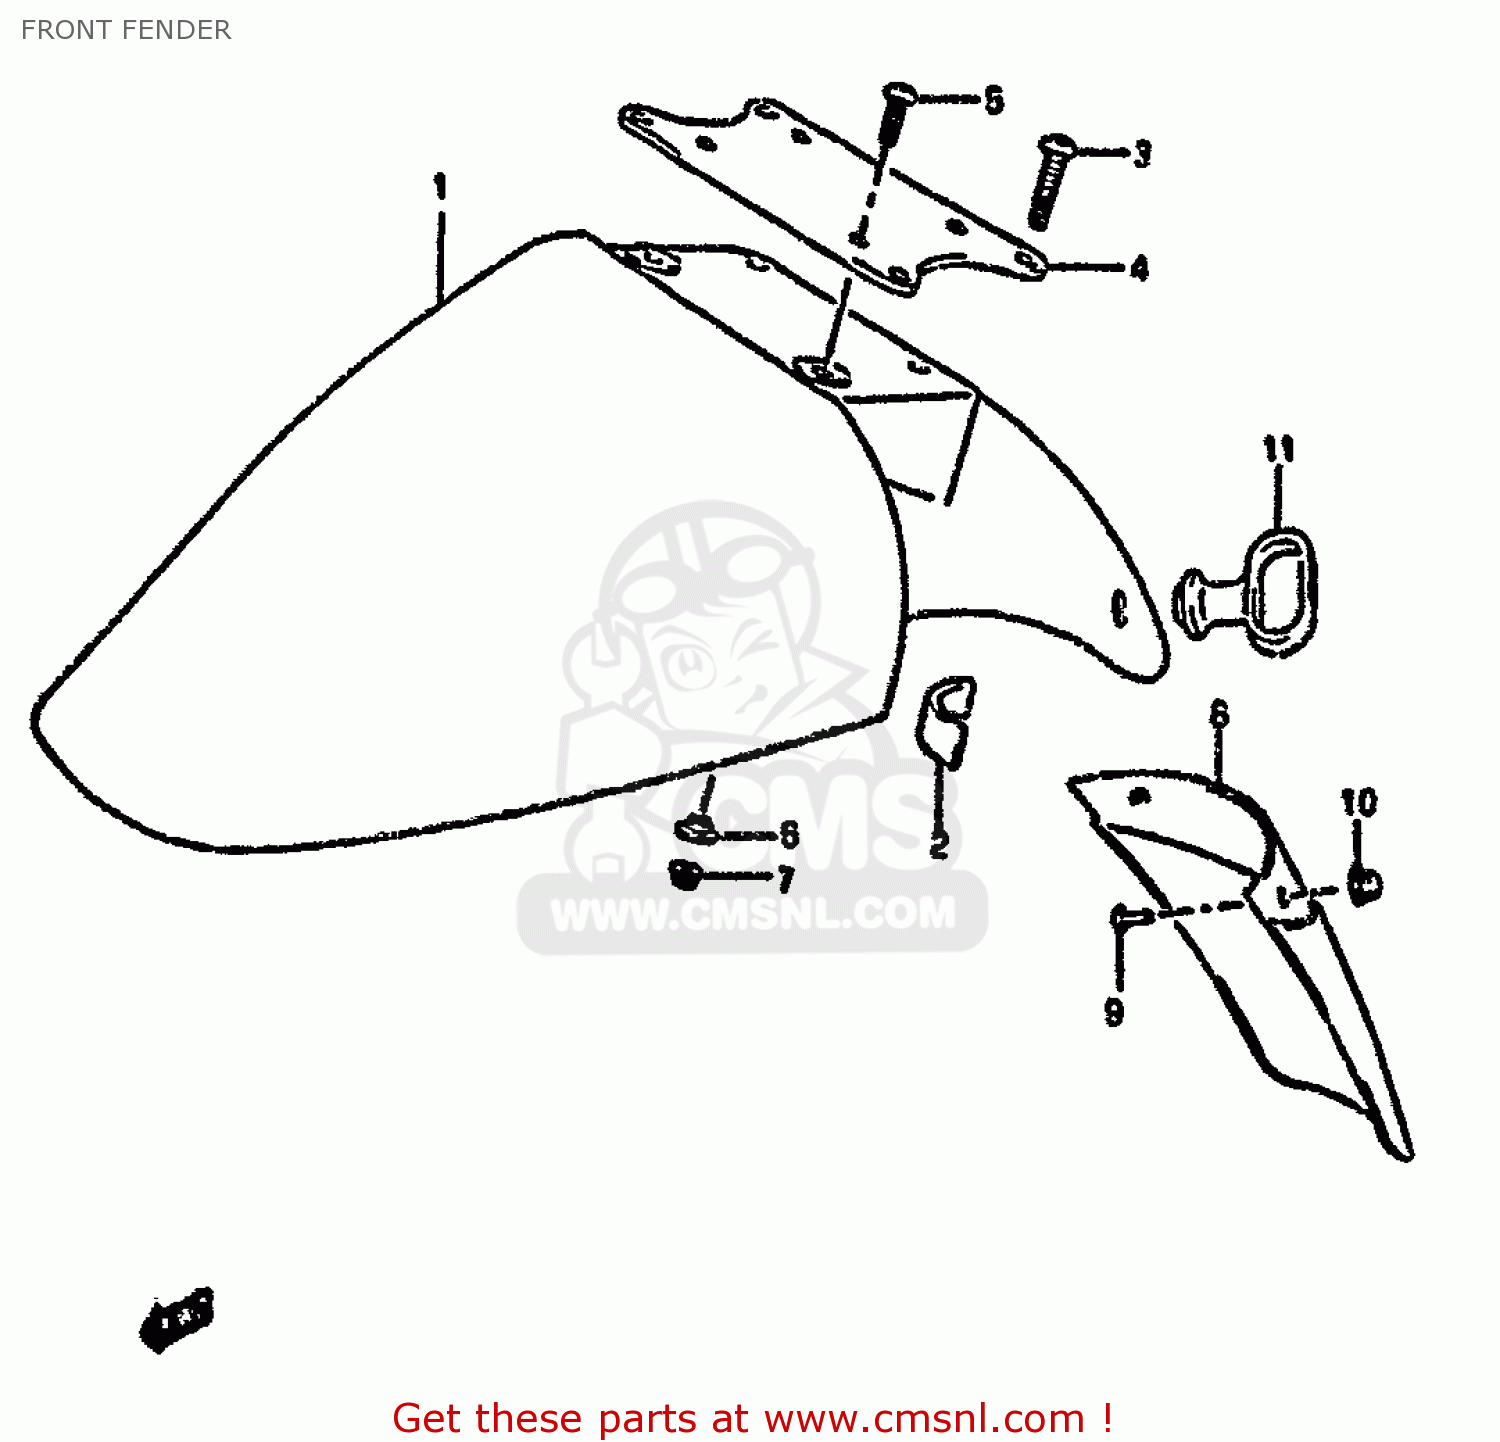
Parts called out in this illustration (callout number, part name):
1	FENDER,FRONT
2	CUSHION,BODY COWLING
3	SCREW(6X12)
4	BRACE,FR FENDER
5	SCREW(5X16)
6	WASHER
7	NUT
8	EXTENSION,FR FENDER
9	SCREW
10	NUT
11	GUIDE,CABLE
